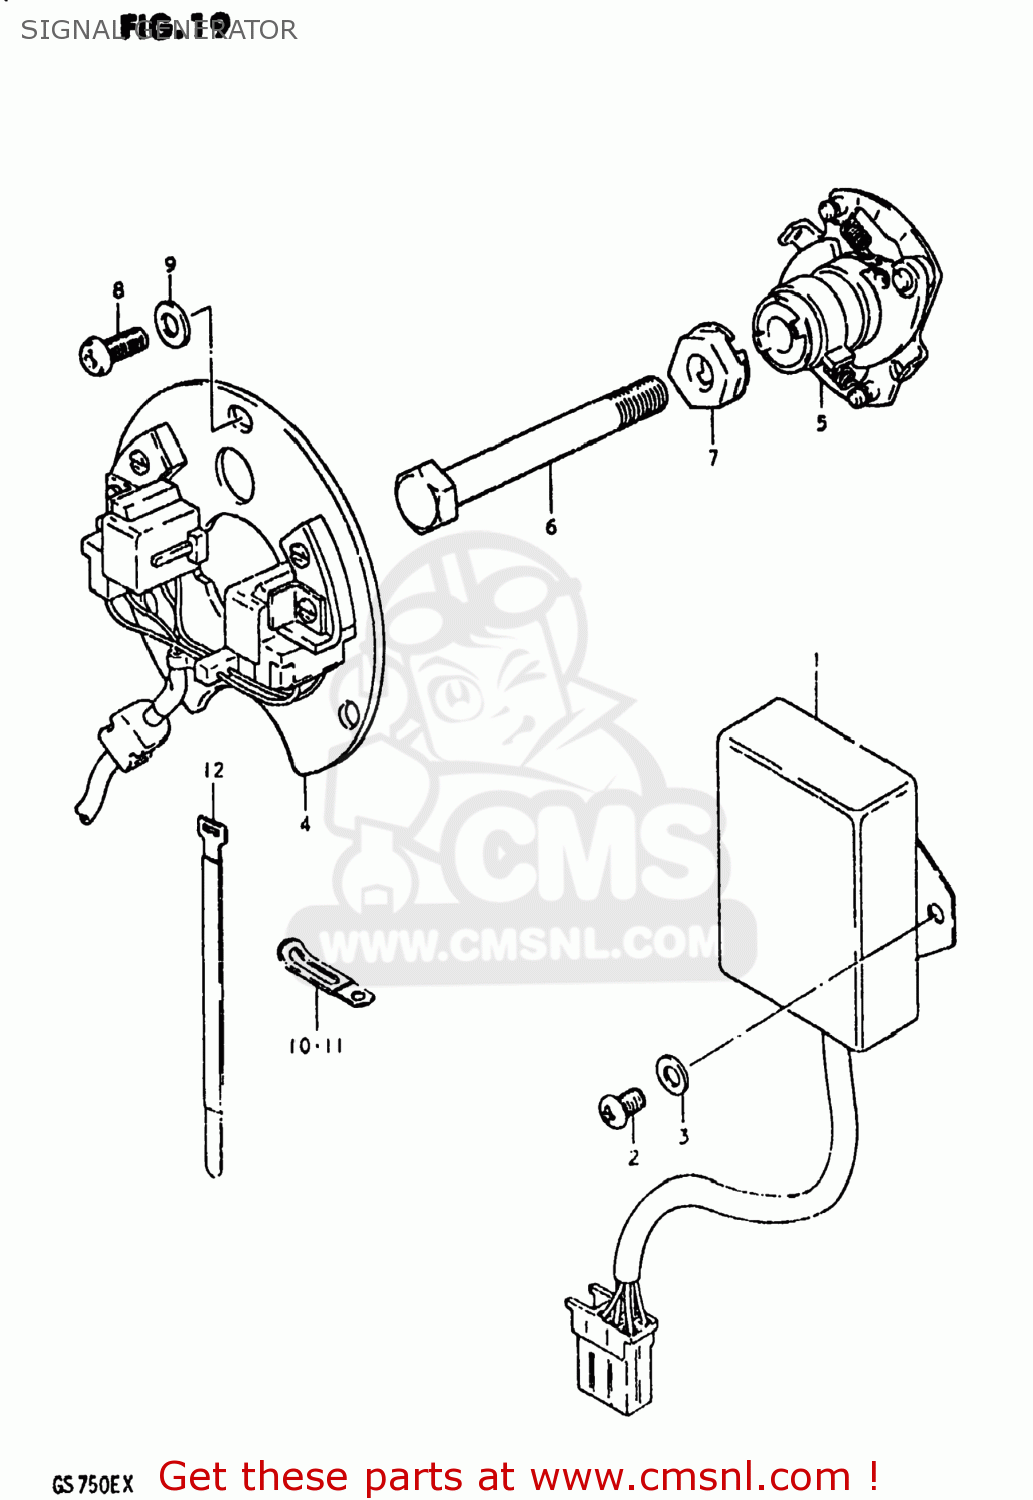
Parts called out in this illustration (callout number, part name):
1	IGNITER UNIT
2	SCREW
3	WASHER
4	SIGNAL GENERATOR ASSEMBLY
5	GOVERNOR ASSEMBLY
6	BOLT
7	WASHER
8	SCREW(5X12)
9	WASHER
10	CLAMP L:35
11	CLAMP
12	CLAMP
